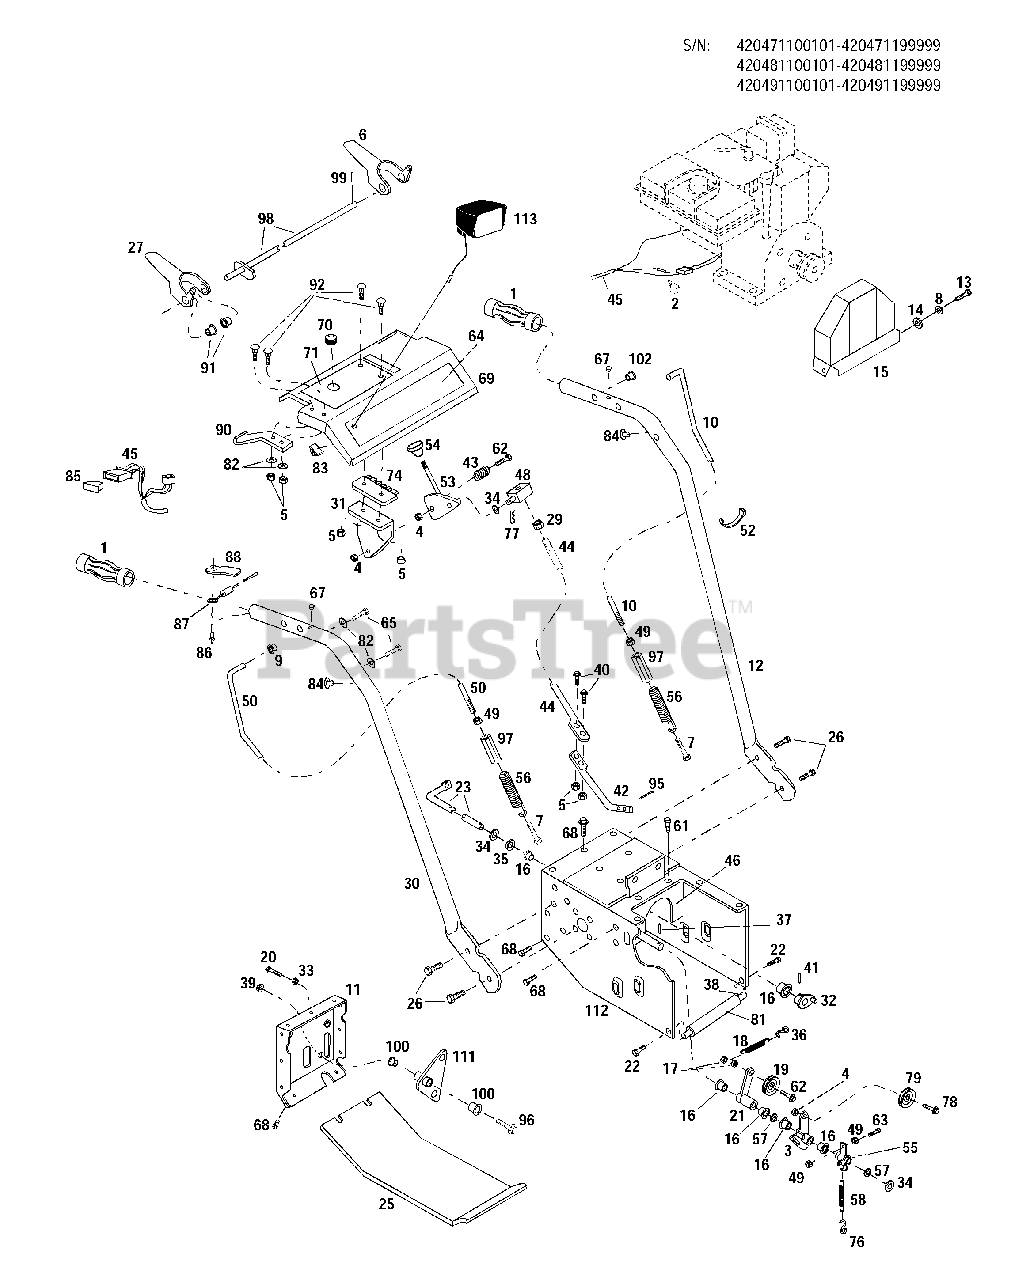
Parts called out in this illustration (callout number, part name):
1	Handle Grip
2	J-Clamp
3	Idler Arm
4	Lock Nut, 3/8-16
5	Lock Nut, 1/4-20
6	Left Control Handle
7	Fillister-Head Bolt, 5/16-18 x 1
8	Lock Washer, 5/16
9	Push Nut
10	Wheel Drive Clutch Rod
11	Back Plate
12	Left Handle Bar
13	Hex Head Bolt, 5/16-18 x 3/4
14	Flat Washer, 5/16
15	Belt Cover
16	Bushing
17	Self-Locking Jam Nut, 3/8-16
18	Extension Spring
19	Idler Pulley
20	Flange Bolt, 5/16-18 x 1-3/4
21	Idler Arm
22	Flange Bolt, 5/16-18 x 3/4
23	Control Arm
25	Bottom Cover
26	Flange Bolt, 3/8-16 x 3/4
27	Right Control Handle
29	Hex Nut, 3/8-16
30	Right Handle Bar
31	Control Bracket
32	Control Arm
33	Jam Nut, 5/16-18
34	Flat Washer, 1/2
35	Bowed Washer
37	Cotter Pin, 3/32 x 1
38	Cross Member
39	Flange Nut, 3/8-16
40	Cap Screw, 1/4-20 x 3/4
41	Drive Pin, 1/8 x 3/4
42	Lower Control Rod
43	Compression Spring
44	Upper Control Rod
45	Wiring Harness
46	Support Assembly
48	Pivot Block
49	Hex Nut, 1/4-20
50	Auger Control Rod
52	Plastic tie
53	Shift Control Arm
54	Knob
55	Brake Arm
56	Extension Spring
57	Flat Washer, 1/2"
58	Extension Spring
61	Flange Bolt, 5/16-18 x 1/2
62	Hex Head Bolt, 3/8-16 x 1-3/4
63	Hex Head Cap Bolt, 1/4-20 x 1
64	Logo Decal
65	Thread-Forming Bolt, 1/4-20 x 5/8
67	Wear Button
68	Thread-Forming Bolt, 5/16-18 x 3/4
69	Console
70	Flip Grommet
71	Instructions Decal
74	Shift Quadrant
77	Cotter Spring
78	Hex Head Bolt, 3/8-16 x 2
79	Idler Pulley
81	Plastic Tubing
82	Flat Washer, 1/4
83	Cord Clip
84	Bushing
85	Connector Body
86	Pop Rivet, 1/8
87	Resistor
90	Flat Spring
91	Flange Bearing
92	Round Head Bolt, 1/4-20 x 5/8
95	Cotter Pin, 3/32 x 3/4
96	Shoulder Bolt
97	Adjusting Nut
98	Control Rod
99	Roll Pin, 1/8 x 5/8
100	Nyliner Flange Bushing
102	Flange Bearing
103	Troy-Bilt Red Spray Paint, 13 oz.
104	Troy-Bilt Black Spray Paint, 13 oz
111	Speed Control Arm
112	Frame
